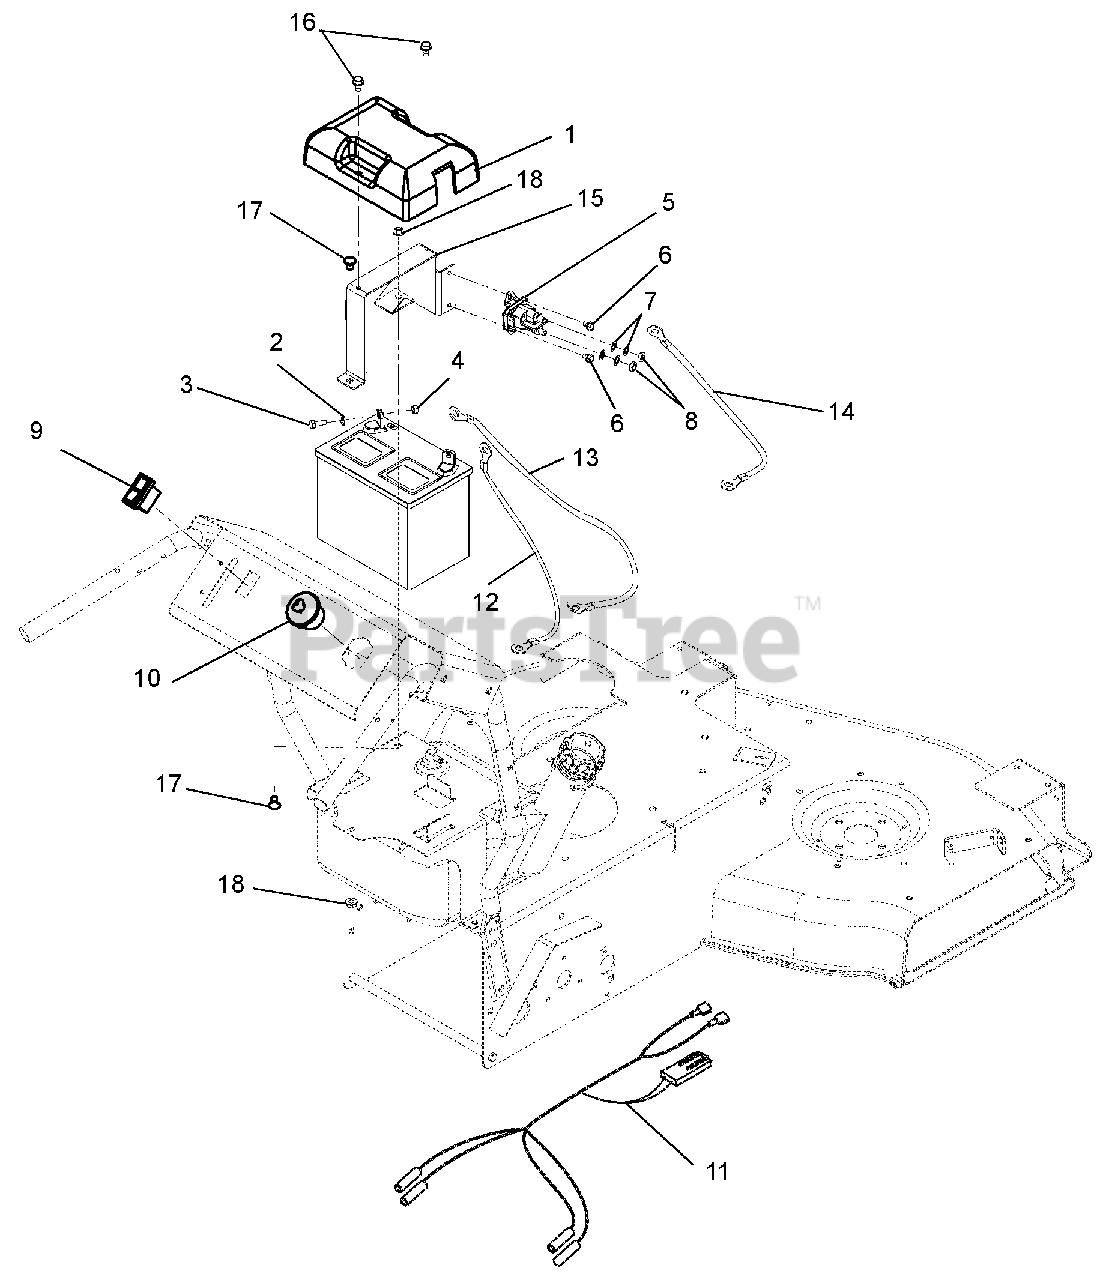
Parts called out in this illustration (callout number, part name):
1	Cover, Battery
2	Washer, Flast Steel .281 x .62 x .065
3	Bolt, Hex .25-20 x .75
4	Nut, KEPS .250-20
5	Solenoid
6	Screw, Tapping Hex Washer Head .250-20 x .37
7	Washer, Internal Lock .31
8	Nut, Jam .31-24
9	Switch, Rocker
10	KEYSWITCH-IGNITION 3 POS
11	Harness, Wiring
12	Cable, Positive Battery 18.50"
13	Cable, Ground 22.0"
14	Cable 6.75"
15	Bracket, Battery Mount
16	Screw, Tapping .31-18 x .50 Hex Washer Head
17	Bolt, Round Head Square Neck .31-18 x .50 Grade 5
18	Nut, Locking-Top-Flange .31-18
